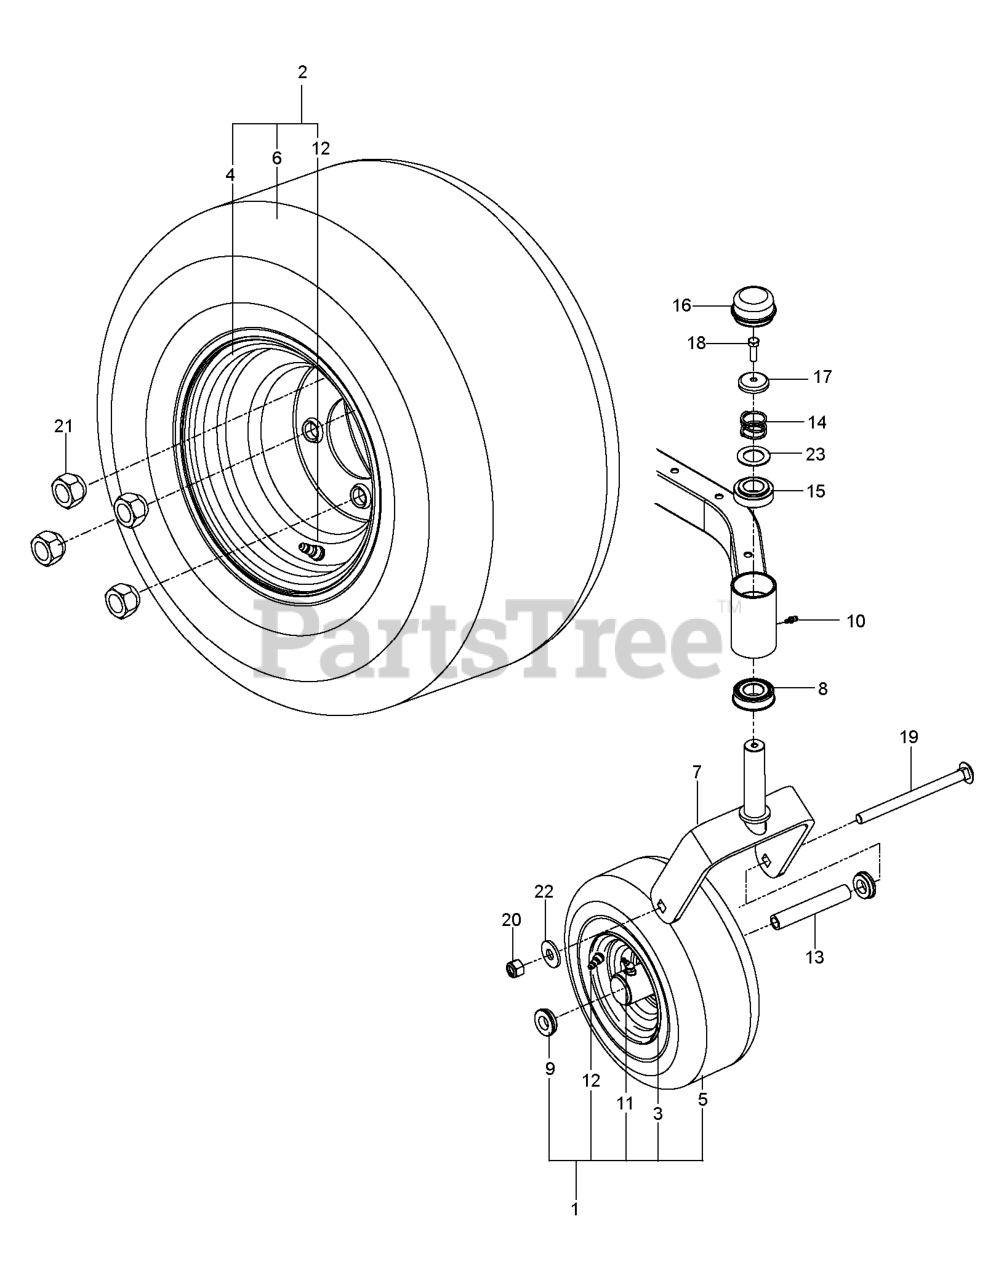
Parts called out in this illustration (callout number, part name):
1	WHEEL ASSY, WIDE, RZ
2	TIRE ASM, 20 X 8-8
4	RIM.8X7.W/8".OFFSET.SILVER.ZTR
5	TIRE.11"X4"-5.4PLY.SMOOTH.KEND
6	TIRE 20 X 8, TURF
7	YOKE.CASTER.ORANGE
8	BEARING FLANGED
9	BUSHING, WHEEL, 3/4"
10	ZERK, 3/16, DRIVE IN
11	ZERK
12	VALVE STEM TR-412
13	SPACER, PIVOT
14	SPRING, CASTER
15	BUSHING, CASTER
16	GREASE CAP
17	CASTER.PLUG
18	5/16-18X1 HHB G5W/NY
19	RHSNB 1/2-13 X 7.5
20	NUT 1/2-13 HEX CNTRLK GR 5 ZD
21	LUG NUT 1/2F
22	WASH USS FLAT 1/2
23	WASHER, 1.025 ID X 1.64
